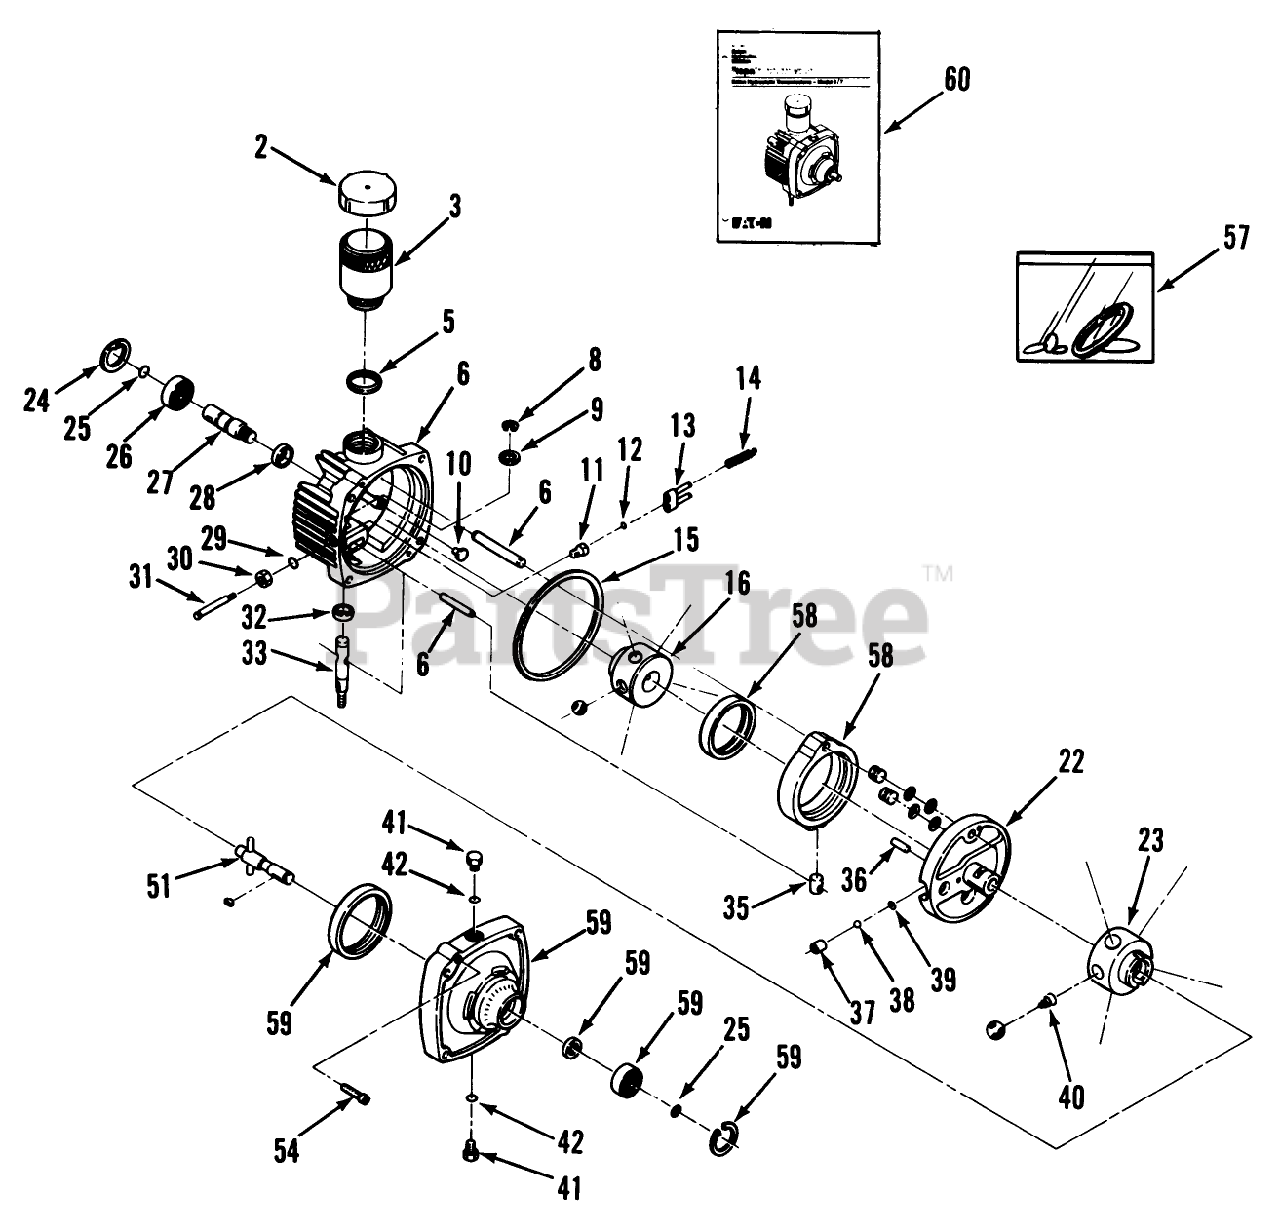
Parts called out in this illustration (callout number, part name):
2	RESERVOIR COVER
3	BODY-RESERVOIR
5	SEAL-RING SQUARE CUT
14	SPRING-VALVE
16	SUB-ASS'Y PUMP ROTOR
25	SNAP-RING
26	BEARING-BALL (INPUT)
27	SHAFT-INPUT
32	SEAL-OIL
57	KIT-OVERHAUL SEALING
59	SUB-ASS'Y BODY
60	Hydrostatic Transmission Repair Manual
